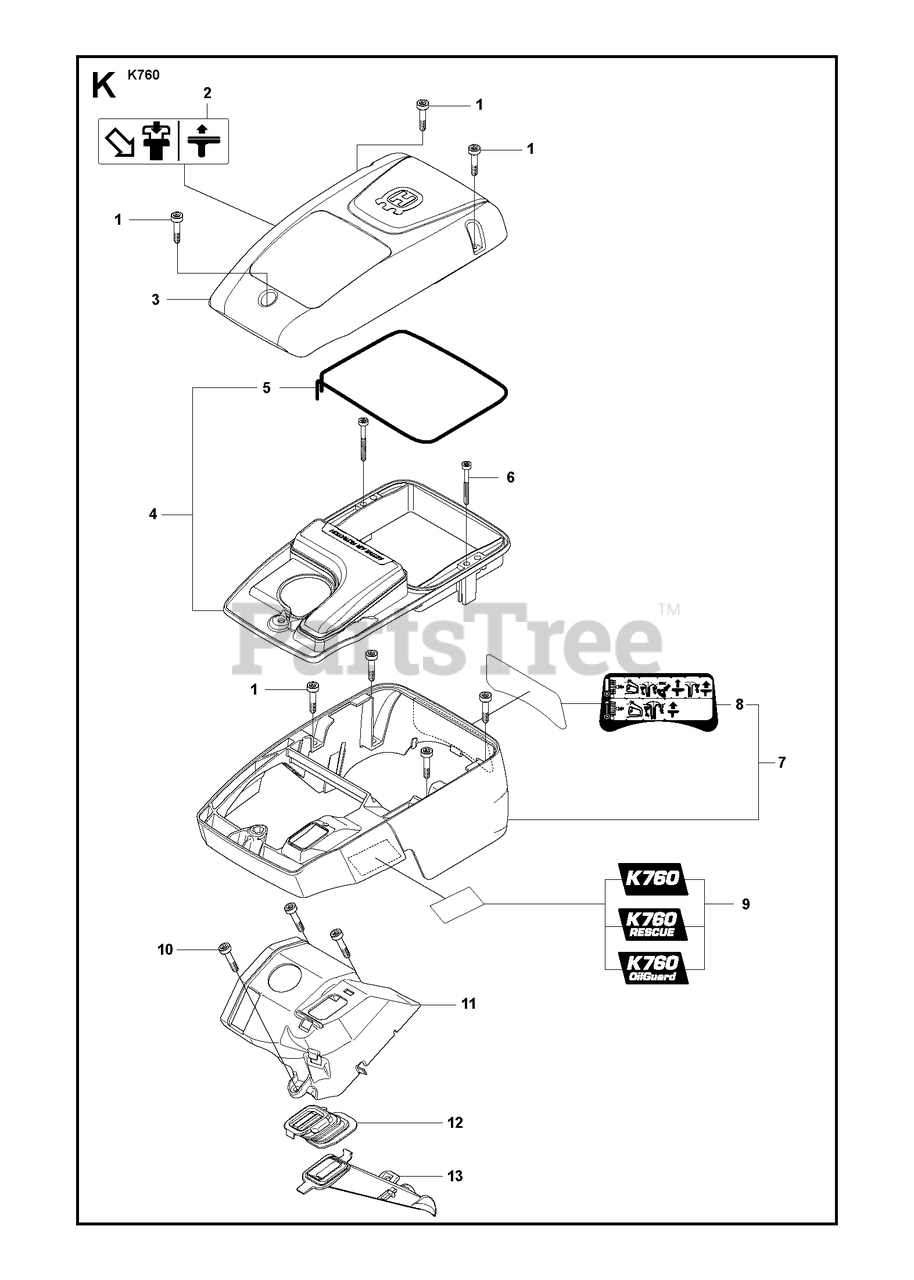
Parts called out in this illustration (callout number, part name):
1	SCREW ITXSCM
3	FILTER COVER
4	FILTER HOLDER ASSYIncl. 5
5	SEALING STRIP
6	SCREW ITXSCM
7	CYLINDER COVER ASSYIncl. 8
9	DECALOil Guard
10	SCREW ITXSCM
11	COVER
12	BELLOWS
